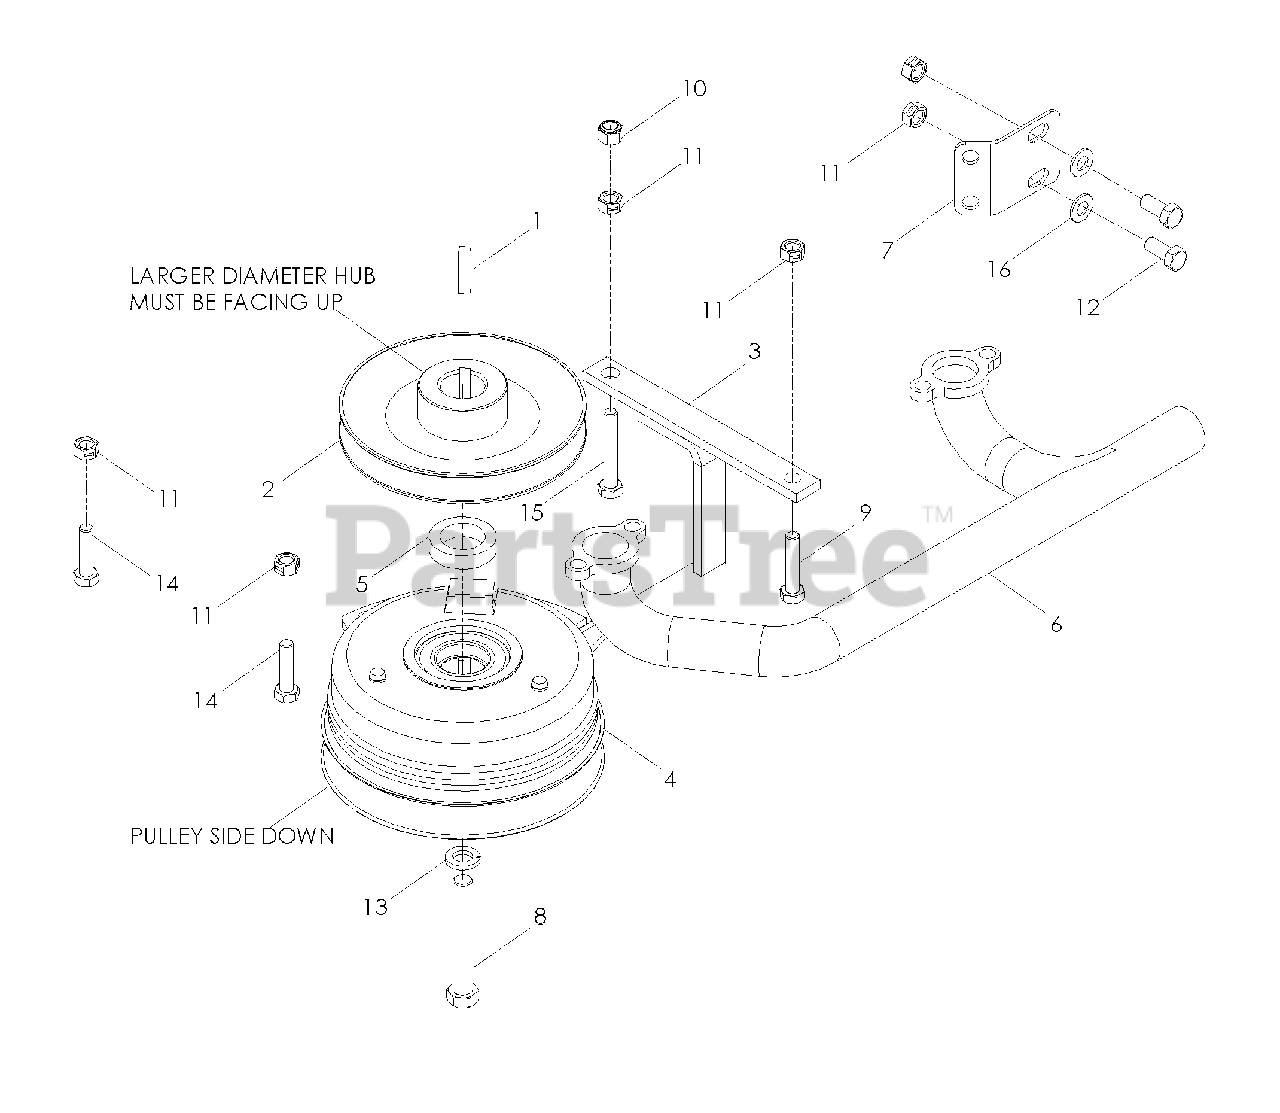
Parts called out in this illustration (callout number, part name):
1	KEY 1/4 SQ x 1 1/8
2	PULLEY, PUMP
3	TIE DOWN, CLUTCH
6	MANIFOLD, EXHAUST
7	BRACKET, MUFFLER
8	HCS 7/16-20 x 3
9	HCS 5/16-18 x 1 1/2
10	NUT 5/16-18 HEX NYLOC
11	NUT 5/16-18 HEX CTRLK
12	HCS 5/16-18 x 3/4
13	WASHER 7/16 SLW
14	HCS 5/16-18 x 1 1/4
15	HCS 5/16-18 x 2
16	WASHER 5/16 SAE FLAT
